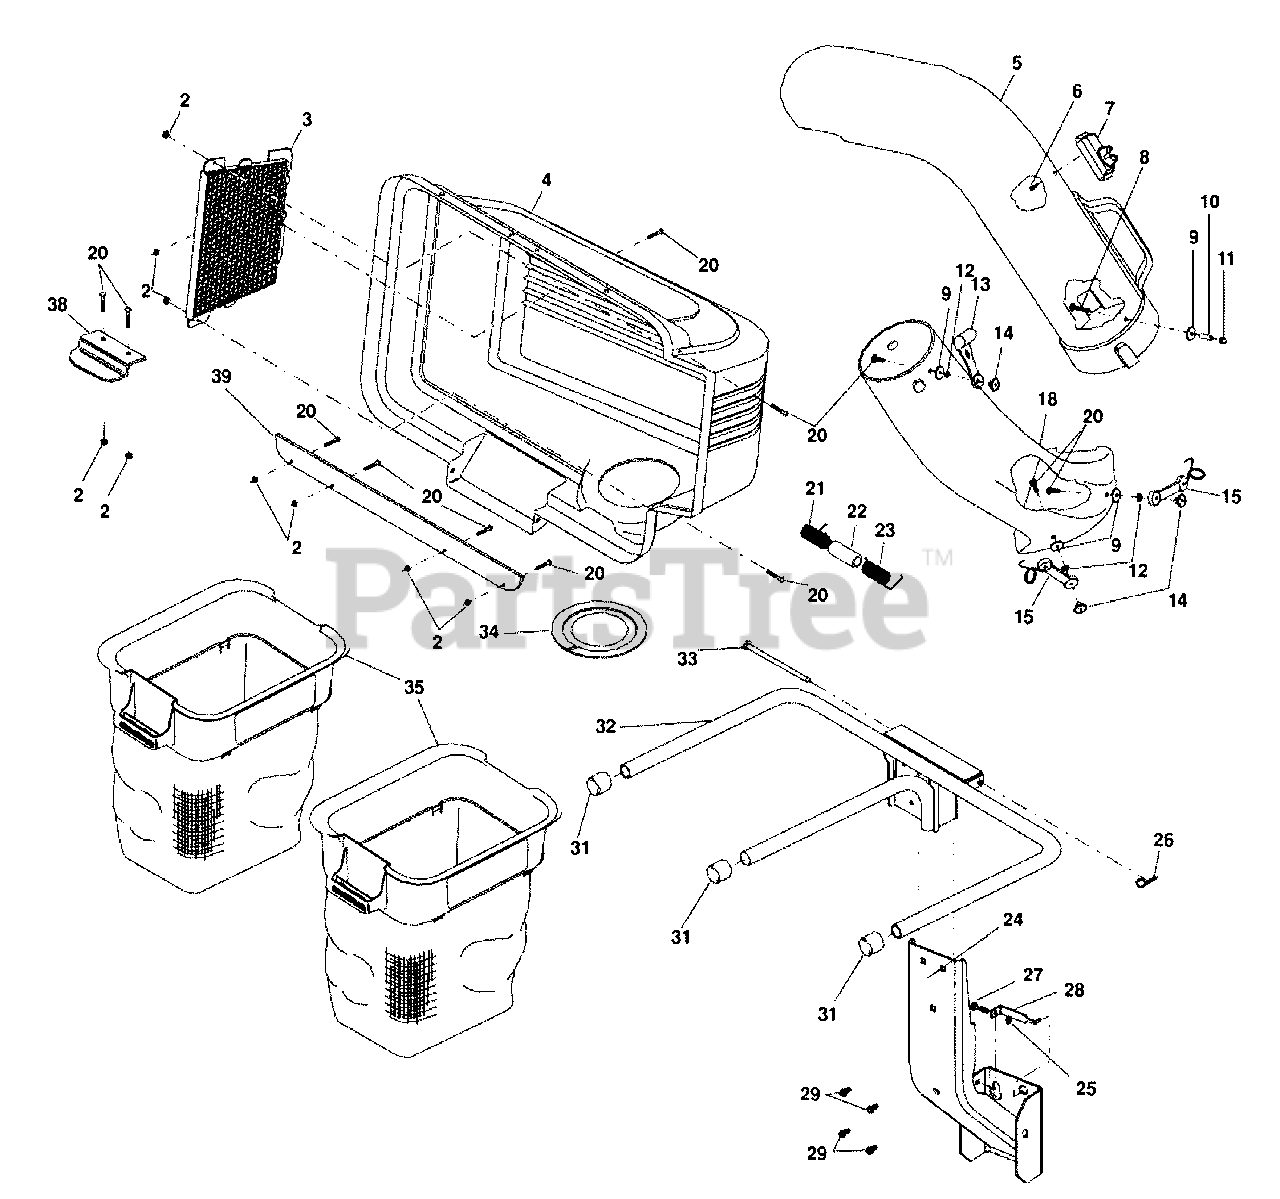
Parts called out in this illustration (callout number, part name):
2	NUT, CROWN LOCK #10-24
3	SCREEN, COVER
4	COVER ASSEMBLY
5	CHUTE, UPPER
6	SCREW, SPECIAL #10-14X1/2
7	FULL BAG INDICATOR
8	SCREW, #10-24 X 1-1/8
9	WASHER 3/16X3/4X16 GA.
10	SPACER, SPLIT
11	NUT, ACORN #10-24
12	WASHER, LOCK
13	LATCH, CHUTE
14	NUT, WELD
15	LATCH, HOOK
18	CHUTE, LOWER
20	SCREW #10-24 X 5/8
21	SPRING, COVER L.H., BLACK
22	SPACER, COVER
23	SPRING, COVER R.H., GRAY
24	SUPPORT ASSEMBLE
25	LOCKNUT
26	SPRING, RETAINER
28	BRACKET, LOCK
29	BOLT, SHOULDER 5/16-18
31	PLUG, TUBING END
32	BAGGER, FRAME
33	PIN, HINGE
34	GASKET, COVER
35	CONTAINER
38	LATCH HANDLE, COVER
39	STRIP, REINFORCEMENT
